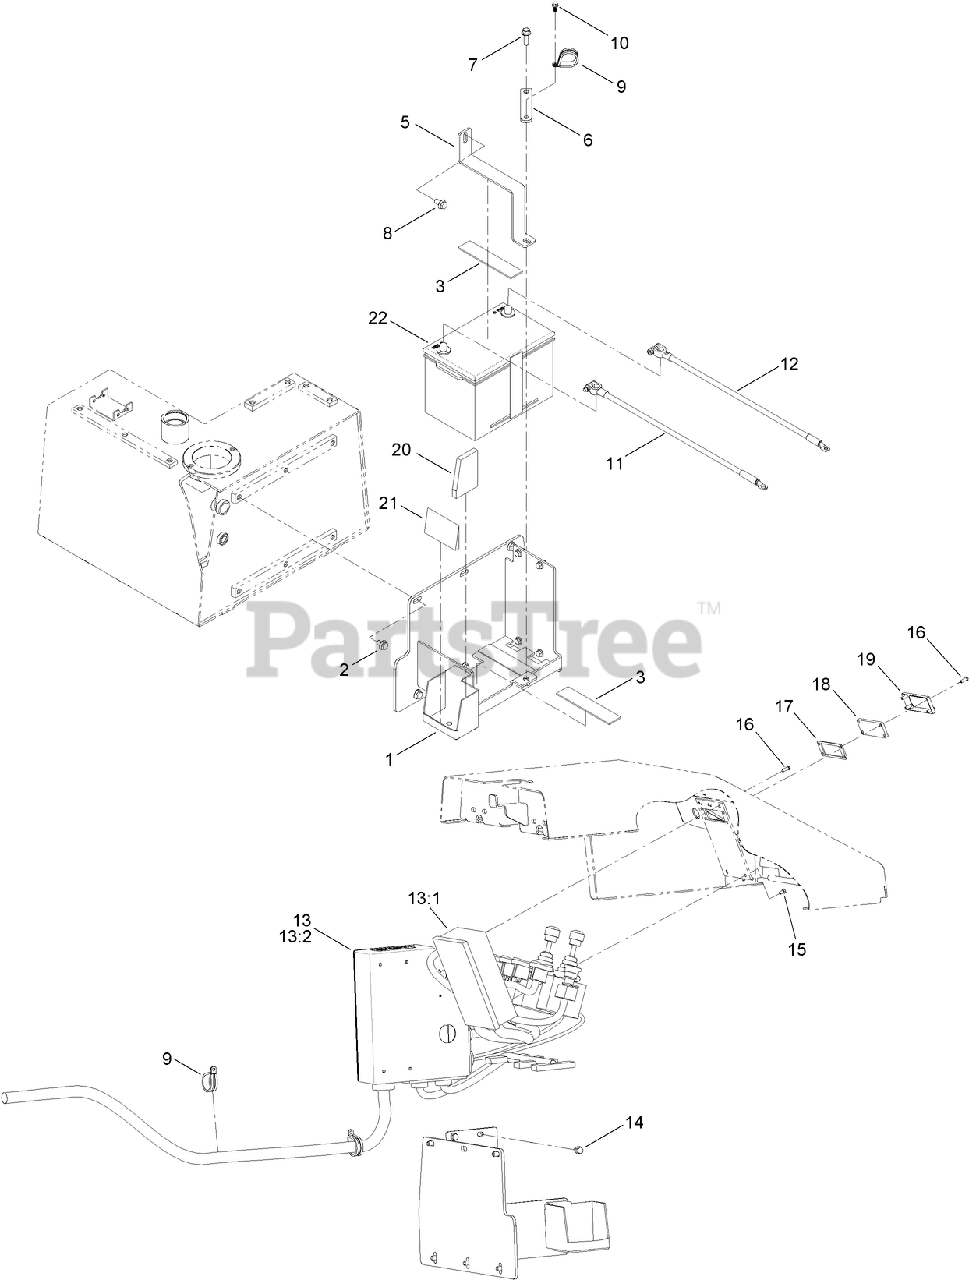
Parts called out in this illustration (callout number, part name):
1	PANEL-ELECTRICAL
2	SCREW-HHF
3	RUBBER
5	STRAP-BATTERY
6	BRACKET-WIRE HARNESS
7	SCREW-HHF
8	SCREW-HHF
9	CLAMP
10	SCREW-HHF
11	CABLE-BATTERY, NEGATIVE
12	CABLE-BATTERY, POSITIVE
13	CONTROL SYSTEM KIT
13:1	BOX-CONTROL IGNITION, ELECTRONIC
13:2	JUNCTION BOX ASM
14	SCREW-HHF
15	SCREW-HH
16	SCREW-HSBH
17	GASKET-COVER
18	COVER
19	COVER-LENS
20	PAD-FOAM
21	PAD-FOAM
22	BATTERY-DRY CELL
